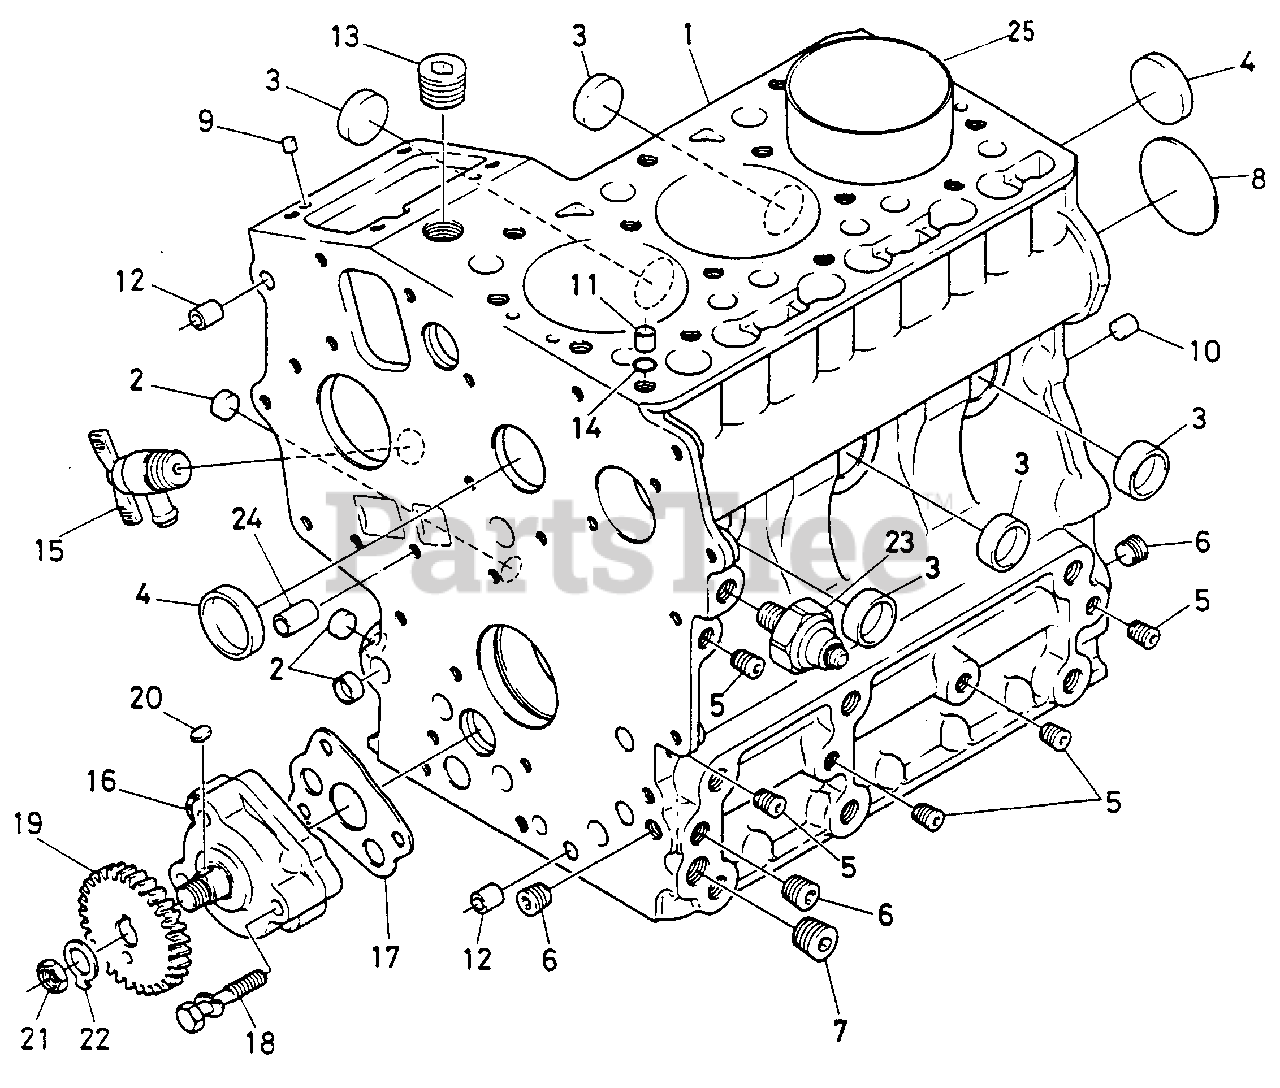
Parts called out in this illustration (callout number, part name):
1	Crankcase Assy
9	Pin, Straight
10	Pin, Straight
15	Handle, Drain Cock
17	Gasket, Oil Pump
19	Gear, Oil Pump Drive
23	Switch, Oil
25	Lining, Cylinder
